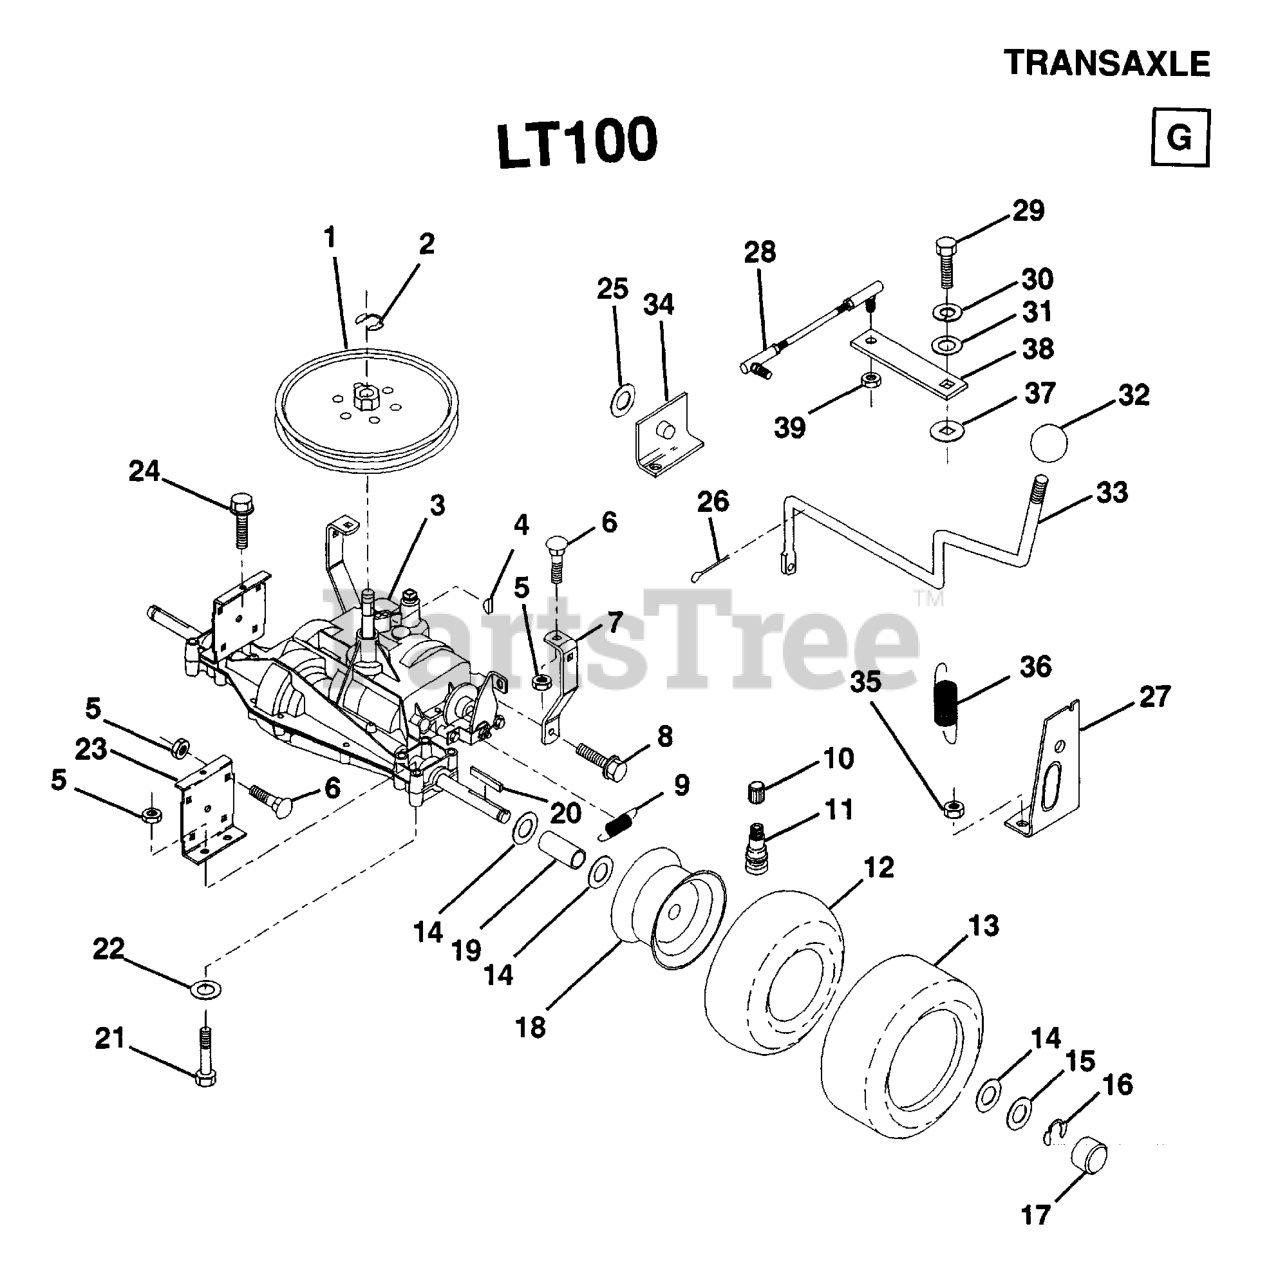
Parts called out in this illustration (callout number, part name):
2	RETAINING RING LT
3	Transaxle, Peerless 4 speed Model No. 930-026
4	KEY STD (1373) DANA
5	LOCKNUT
6	RP BOLT 5/16-18 X3/4 ZN/YEL GR
7	STRAP,TORQUE
8	Screw 5/16-18 x 1/2 Hex, Self Tapping 5/16-18 x 1/2
9	SPRING T
11	VALVE STEM LT
12	TUBE.16X6.5/7.5-8
17	CAP.HUB.FRONT.LT.BLACK
20	SQUARE KEY
21	Bolt, Hex, Fin. 5/16 x 18 UNC x 2-1/2
22	WASHER
23	BRKT,TRANSAXLE
24	BOLT
26	PIN COTTER
27	SUPPORT HANDLE SHAFT RH
30	LOCKWASHER
31	WASHER
32	KNOB T (1/2-HOLE)
33	ROD, SHIFT
34	SUPT, HDLE SHT LH
35	LOCKNUT
36	SPRING.EXTENSION
37	WASH-SHFT PLT LT
39	LOCKNUT
